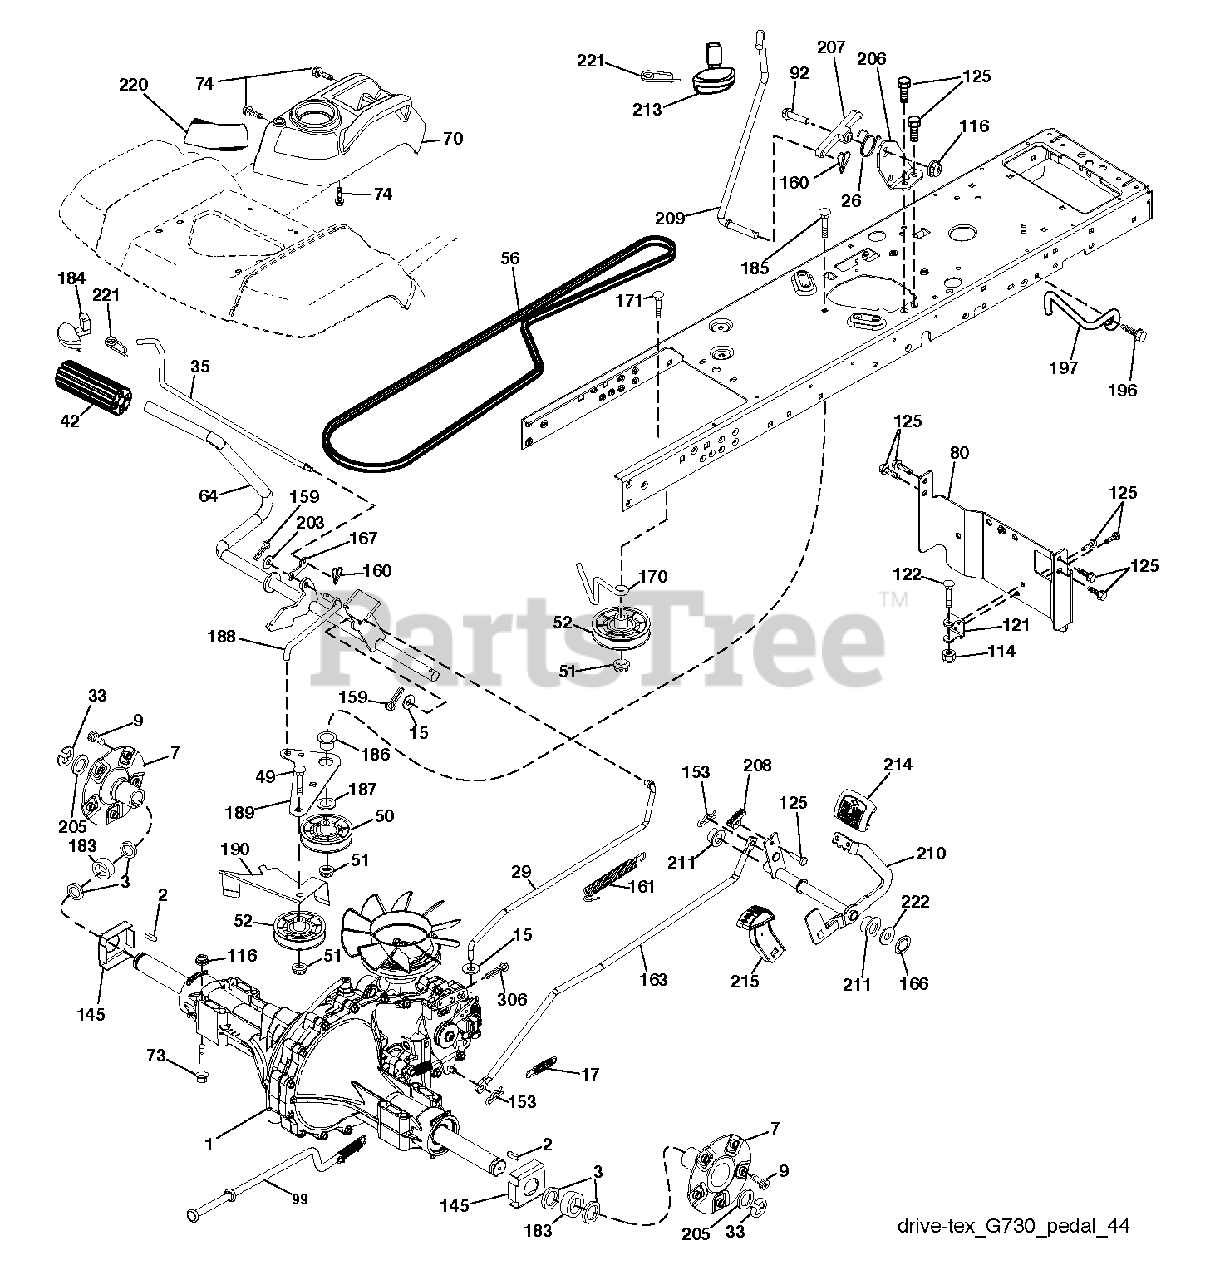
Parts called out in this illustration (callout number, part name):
2	KEY, 1/4 SQ X 1 1/4
7	HUB.PNT.GT.PM.1IN.AXLE.E-DIP
15	WASHER
17	SPRING.BRAKE.HG3000/3500
26	SPRING.RETURN.CRUISE
33	E RING HYT
35	ROD ROD.PARKINGBRAKE.GT.HUSQ/P
42	PEDAL COVER T
50	IDLER.FLAT.910.OFFSET
51	NUT LOCK FLG 3/8-16 UNC
52	IDLER.V-GROOVE.910.OFFSET
56	DRIVE BELT, LTH & YTH TRACTORS
64	SHAFT.ASM.PEDAL.BRK.CNTR
70	CONSOLE.ASM.RH.GT.FC.HUSQ
73	BOLT HEX FLGHD 5/16-18X3 GR. 5
74	SCREW.HI-LO.CONSOLE
80	STRAP.TORQUE.YT.G700
92	BOLT
99	ROD ASSY BYPASS G730
114	NUT.71038.31-18.HEX.NYLOCK
116	NUT LOCK HEX FLANGE 5/16-18
121	BRACKET STRAP TORQUE
122	Bolt RDHDSQ 5/16-18 Unc x 2-1/2
125	SCREW
145	WASHER.AXLE.FLANGE.HG-3000
153	RETAINER M
159	COTTER PIN
160	RETAINER CLIP
161	SPRING, RETURN LT
163	ROD PEDAL CONTROL
166	NUT.PUSH.625
167	LATCH.BRAKE.SPRING
170	KEEPER.V-IDLER.CENTER.
183	SPACER.SPLIT.1.000ID X 1.500
184	HANDLE.PARKING.BRAKE.H (BLK)
186	SPACER.RETAINER
187	WASHER 12/32X2X10GA
188	LINK.CLUTCH.GROUND DRIVE.LONG
189	BELLCRANK.GROUND.DRIVE.TEX.
190	KEEPER.BELLCRANK.DRIVE
196	SCREW 3/8-16X1
197	CLUTCH.ANTIROTATION.WIREFORM.
203	WASHER
206	BRACKET.MOUNT.CRUISE.LATCH
207	LATCH.CONTROL.CRUISE.TEX
208	GEAR.SECTOR.CONTROL.CR
209	ROD ROD.CRUISECONTROL.GT.HUSQ/
210	ROCKER.ASM.PEDAL.CONTR
211	BEARING.NYLON
213	KNOB.CONTROL.CRUSIE.HU
214	PEDAL.FORWARD.PAD.TEX
215	PEDAL.COVER.REVERSE.CRD.X428BK
220	REFLECTOR.RH.TEX GT
221	RETAINER.SPRING.CLIP.H
222	WASHER 21/32 X 1-1/4 X 10 GA.
306	PIN COTTER
